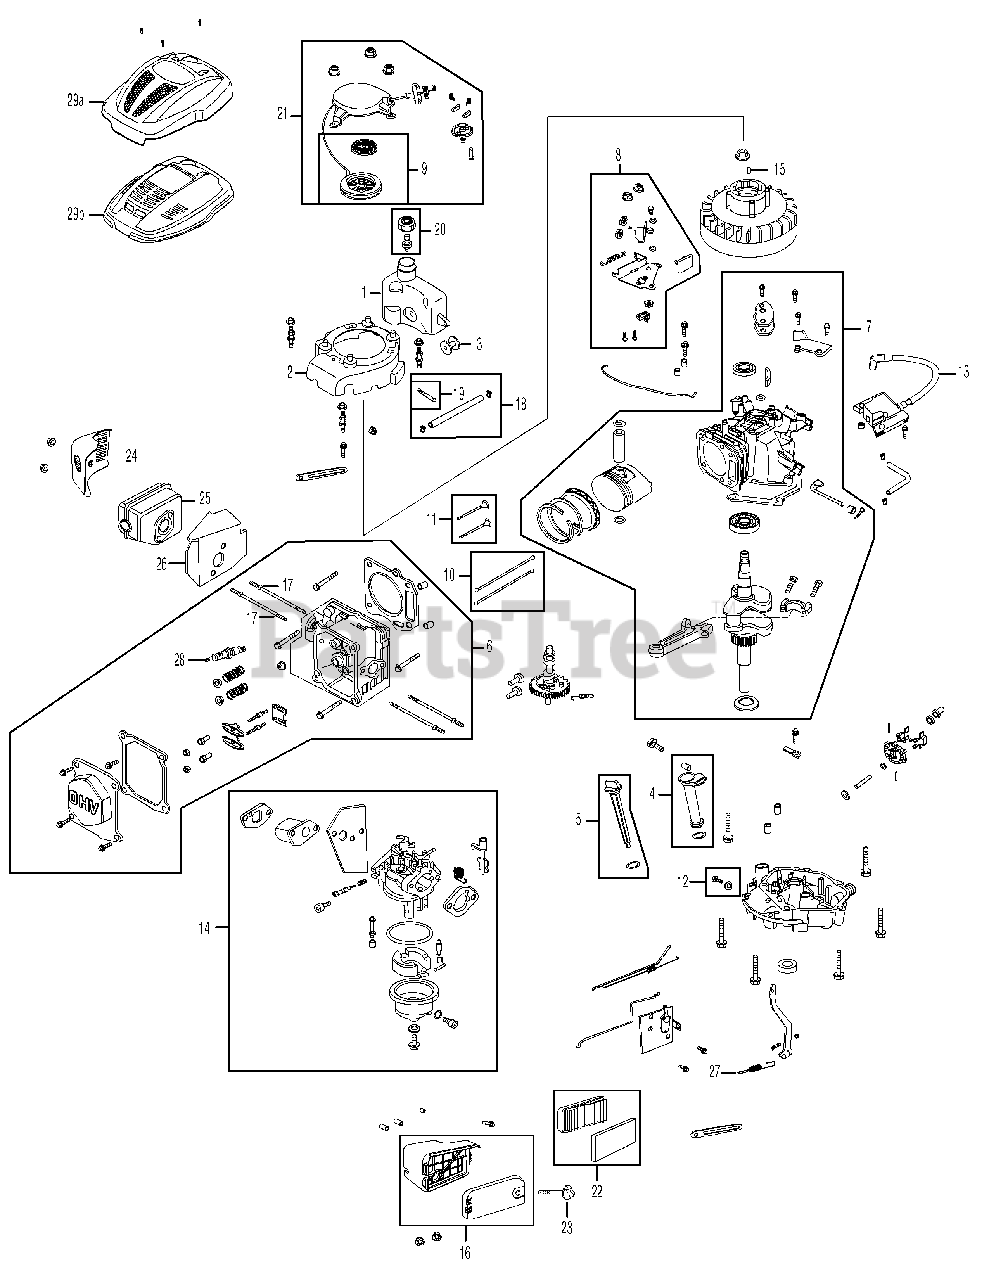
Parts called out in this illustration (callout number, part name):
1	Fuel Tank
2	Flywheel Shroud
3	Rubber Fuel Tank Mounting Washer
4	Oil Filler Tube Assemlby
5	Dipstick Assembly
6	Cylinder Head Complete
7	Short Block Assembly
8	Stop Switch and Brake Assembly
9	Recoil Spring and Pulley Assembly
12	Oil Drain Plug and Washer Assembly
13	Ignition Coil
14	Carburetor Assembly
15	Flywheel Key
16	Air Cleaner Housing Assembly Complete
17	Muffler Stud Assembly
18	Fuel Line Kit - Inc. hoses, clamps & filter
19	Fuel Filter
20	Fuel Cap Assemlby
21	Recoil Starter Assembly
22	Air Cleaner Kit
23	Air Cleaner Thumb Screw
24	Muffler Guard
25	Muffler
26	Muffler Gasket & Heat Shield
27	Governor Return Spring
28	Spark Plug
